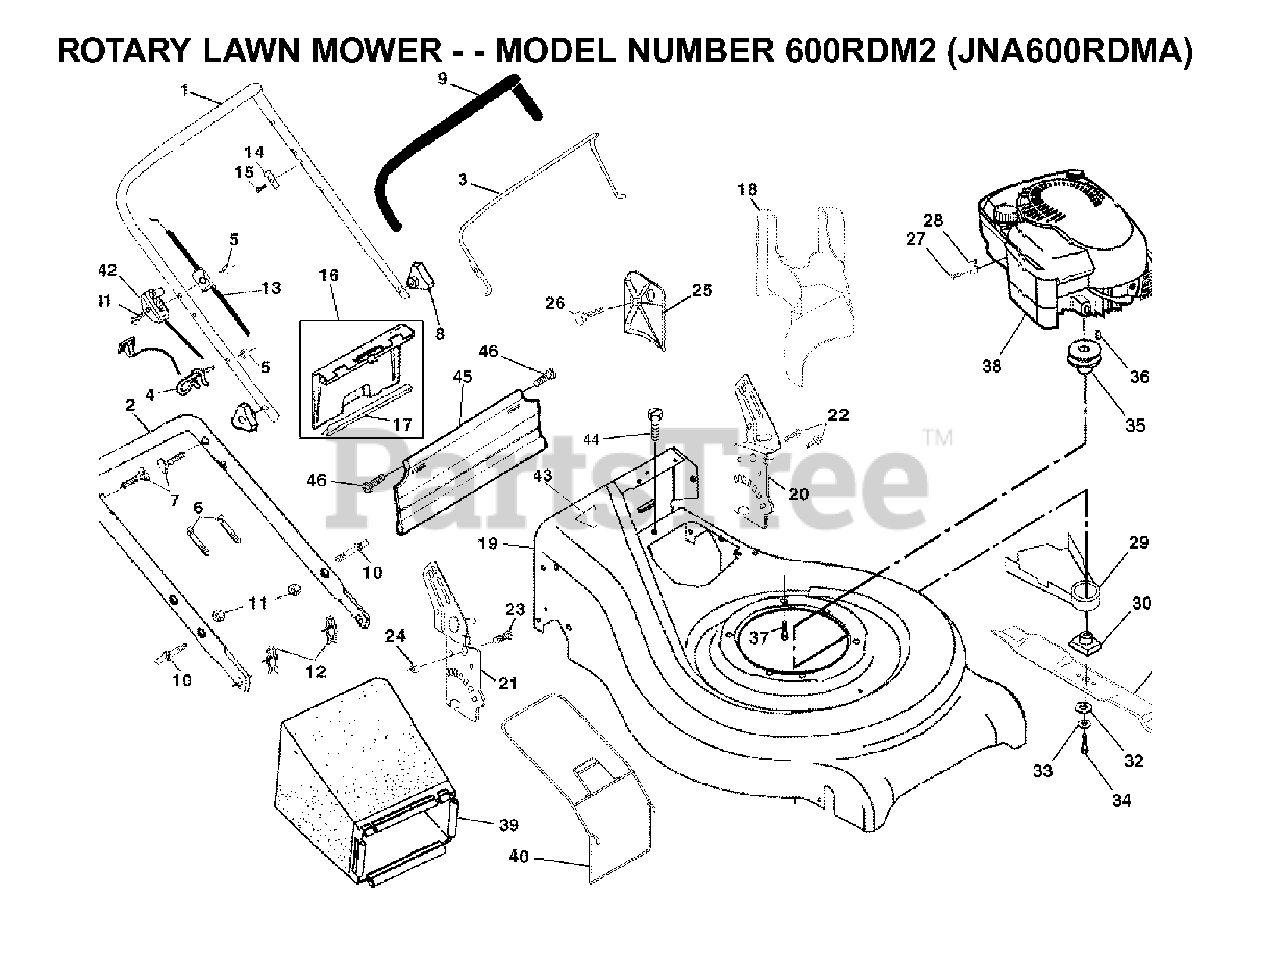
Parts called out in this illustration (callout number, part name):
1	CABLE DRIVE
2	BAIL.CONT.DR.21.RWGD.BLACK
3	DOWNSTOP BRACKET
4	SCREW.HEX.HEAD.WASHER.10-16
5	DRIVE COVER
8	FLANGED LOCKNUT 3/8-16 ZINC
13	TRANSMISSION ASM. (WALK)
14	PIN.SPRING.THRUST
15	THRUST WASHER
16	ROD CONNECTING
17	SPRING
18	SPRING
19	KNOB
21	RP BEARING SUPPORT
22	BEARING, BALL
23	BRACKET
26	DRIVE PINION
28	E-RING 7/16 RE
29	DUST SHROUD PM
30	WASHER FLUT
33	HEX FLANGE LOCKNT
34	WAVE WASHER
35	SHAFT ASSY
36	SHAFT ASSY
37	RETAINER.FRONT.SHAFT
39	RETAINER CLIP
40	WHEEL ASMBLY FRONT
41	CAP.HUB.ARC.SPOKE.8".LP
44	WASHER
45	BELLEVILLE WASHER
